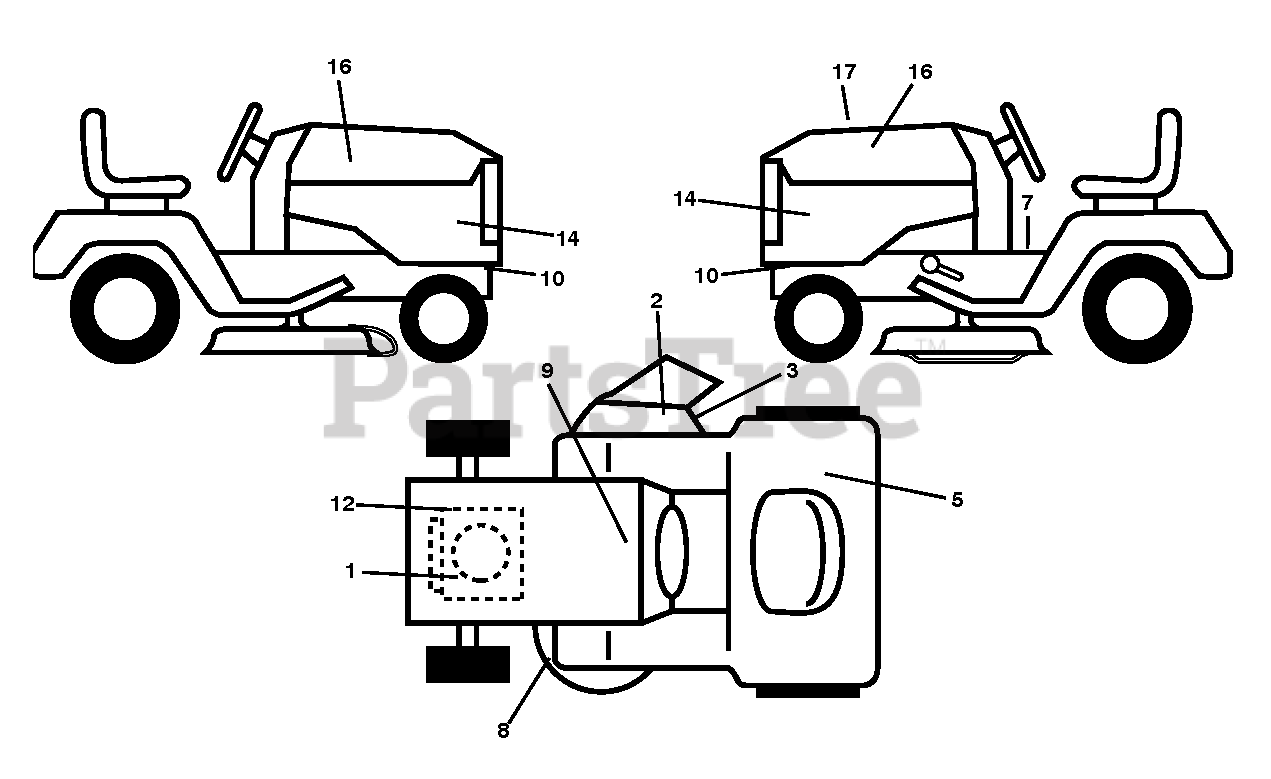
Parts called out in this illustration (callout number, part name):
1	DECAL DECAL.ENG.BS.ENDUR.22HP.
2	DECAL, DECK DEFLECTOR, WARNING
3	DECAL.DFLCTR.WARNNG.CTFNGR.SYM
5	DECAL CERTIFICATION DECAL EMCC
7	DECAL.TRAC.FNDR.GLBLWRNG.RDYST
8	DECAL.V-BELT.SCH.42/46"MEC/ELE
9	DECAL BTRY SYMBOLS
10	DECAL.CHASSIS.HOT.MUFFLER
12	DECAL.ENGINE.WARNING
14	DECAL.SDPNL.HUSQGT.TS246.RH/LH
16	DECAL.BADGE.170MM.TEXTLOGO.
